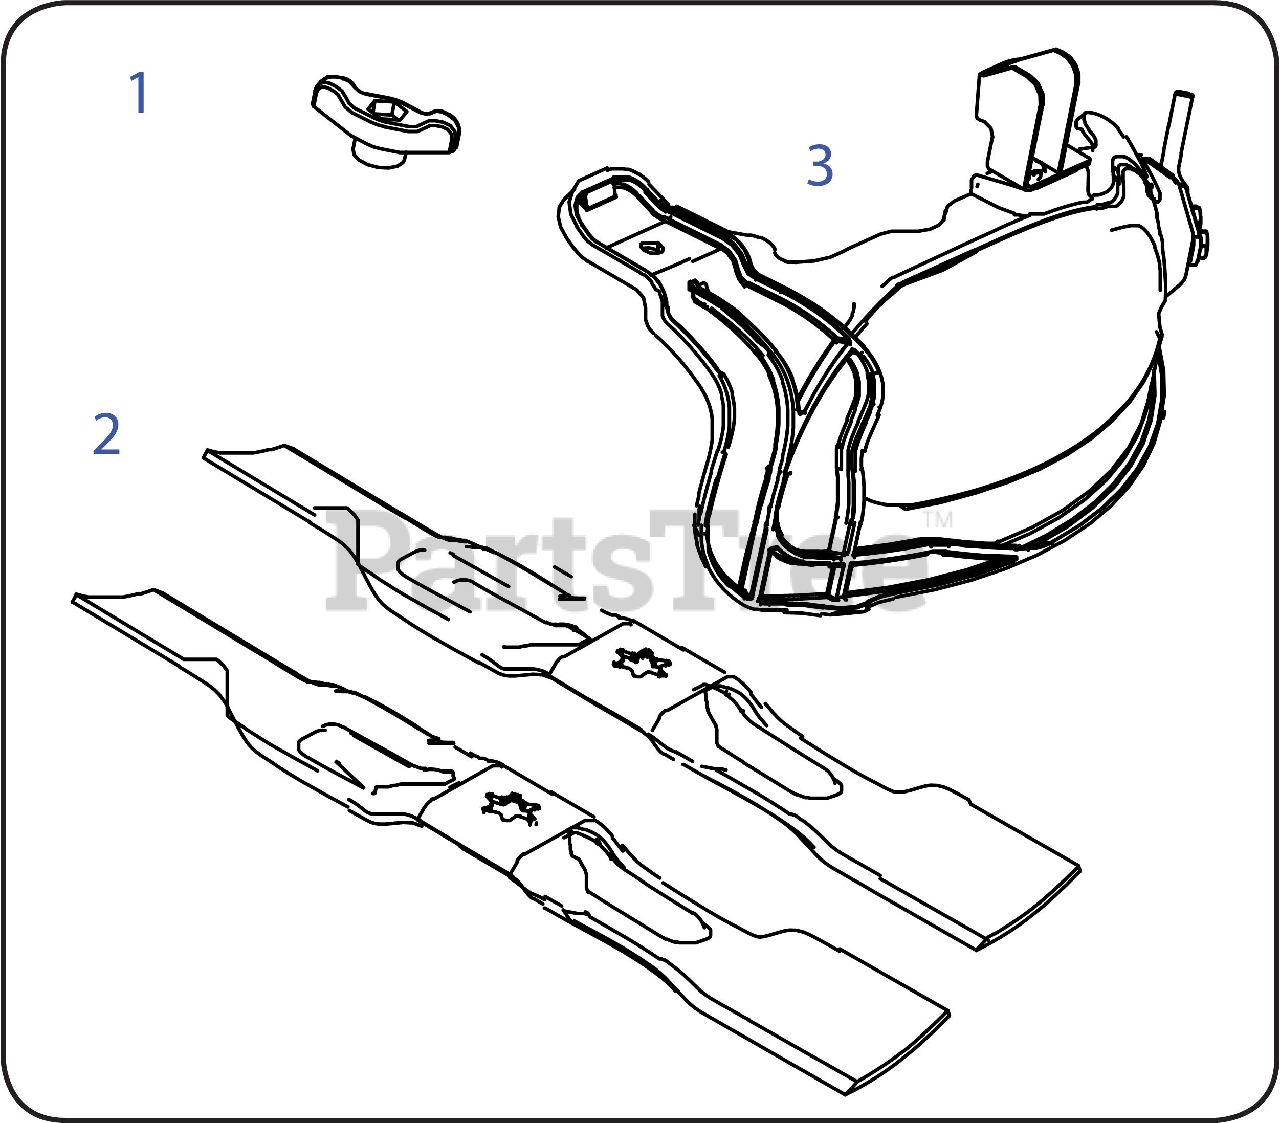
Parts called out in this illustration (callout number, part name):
1	WING KNOB 5/16-18
2	17.27" BLADE (MULCH)
3	34" MULCH PLUG ASSEMBLY
